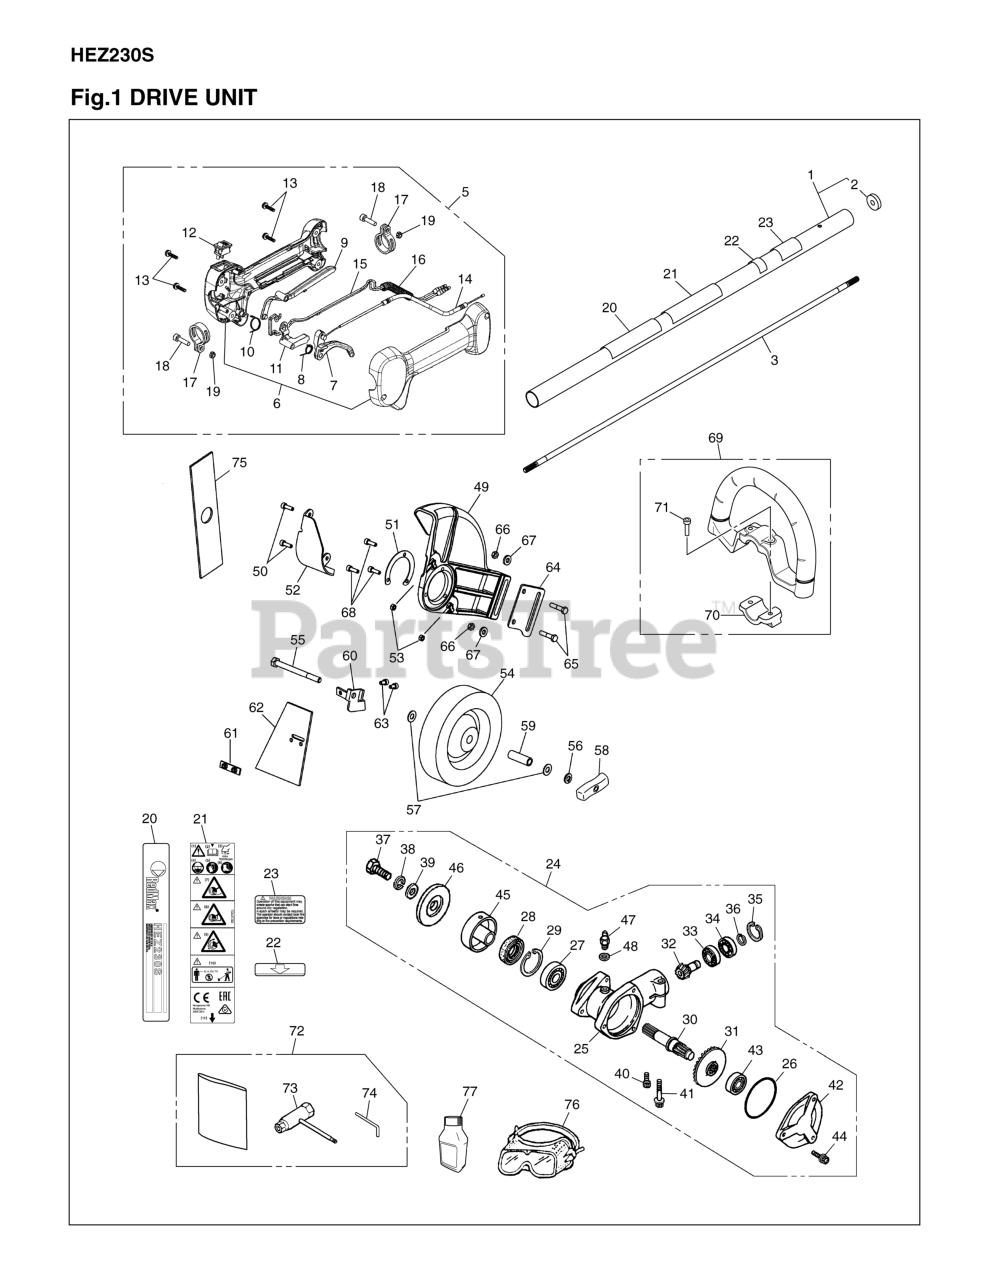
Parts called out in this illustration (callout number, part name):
1	TUBE COMP
3	DRIVESHAFT
5	ASSY THROTTLE
6	GRIP HALF SET
7	LEVER, THROTTLE
8	SPRING, THROTTLE
9	LEVER, SAFETY
11	LEVER JOINT
12	STOP SWITCH NM_09091801
15	CORD - C
19	NUT
23	DECAL SPARK ARRESTOR WARNING
24	GEAR CASE ASSY
25	GEARCASE
28	OIL SEAL
37	BOLT M8 X L25 L/H
41	BOLT,TORX
45	HOLDER (A)
46	HOLDER (B)
49	GUARD
52	PLATE, PROTECTOR
55	BOLT M8 X L65
64	MAIN BRACKET
65	BOLT M8 X L40
66	NUT
68	BOLT T27 M5X16
69	HANDLE LOOP
70	CLAMP HANDLE
72	TOOL KIT
76	GOGGLExxx (RPLS
77	OIL 2 CYCLE ENGINE OIL 2.
